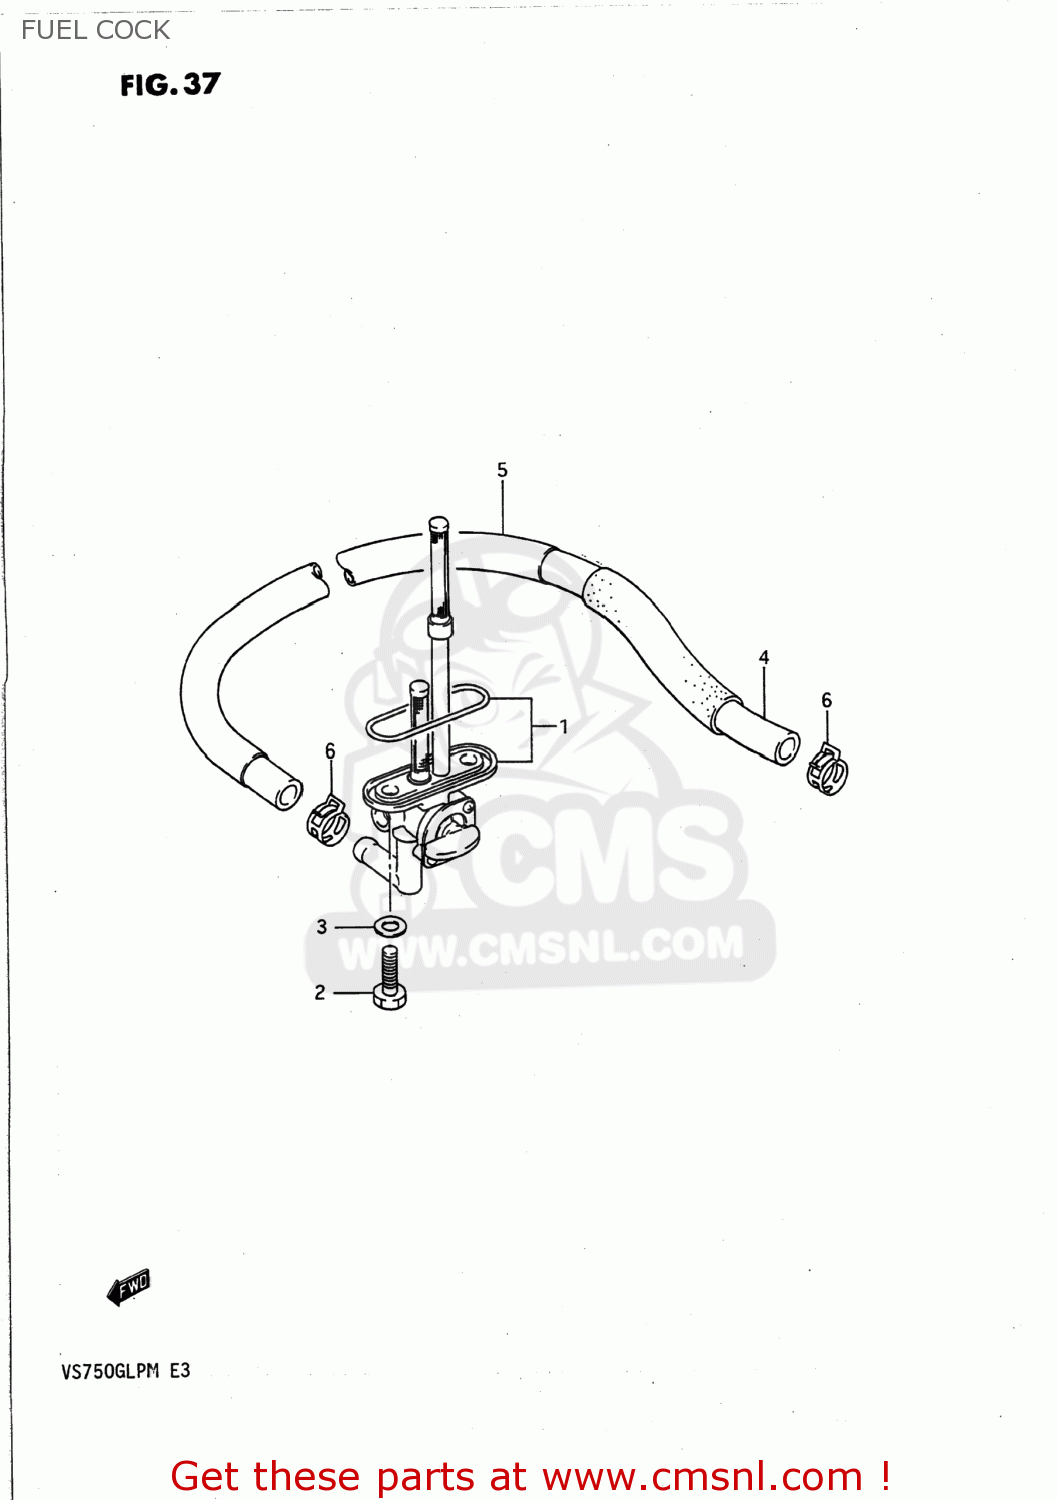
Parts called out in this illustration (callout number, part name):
1	COCK ASSEMBLY,FUEL
2	BOLT(6X20)
3	GASKET
4	HOSE,FUEL PUMP & COCK
5	TUBE,FUEL HOSE
6	CLAMP
